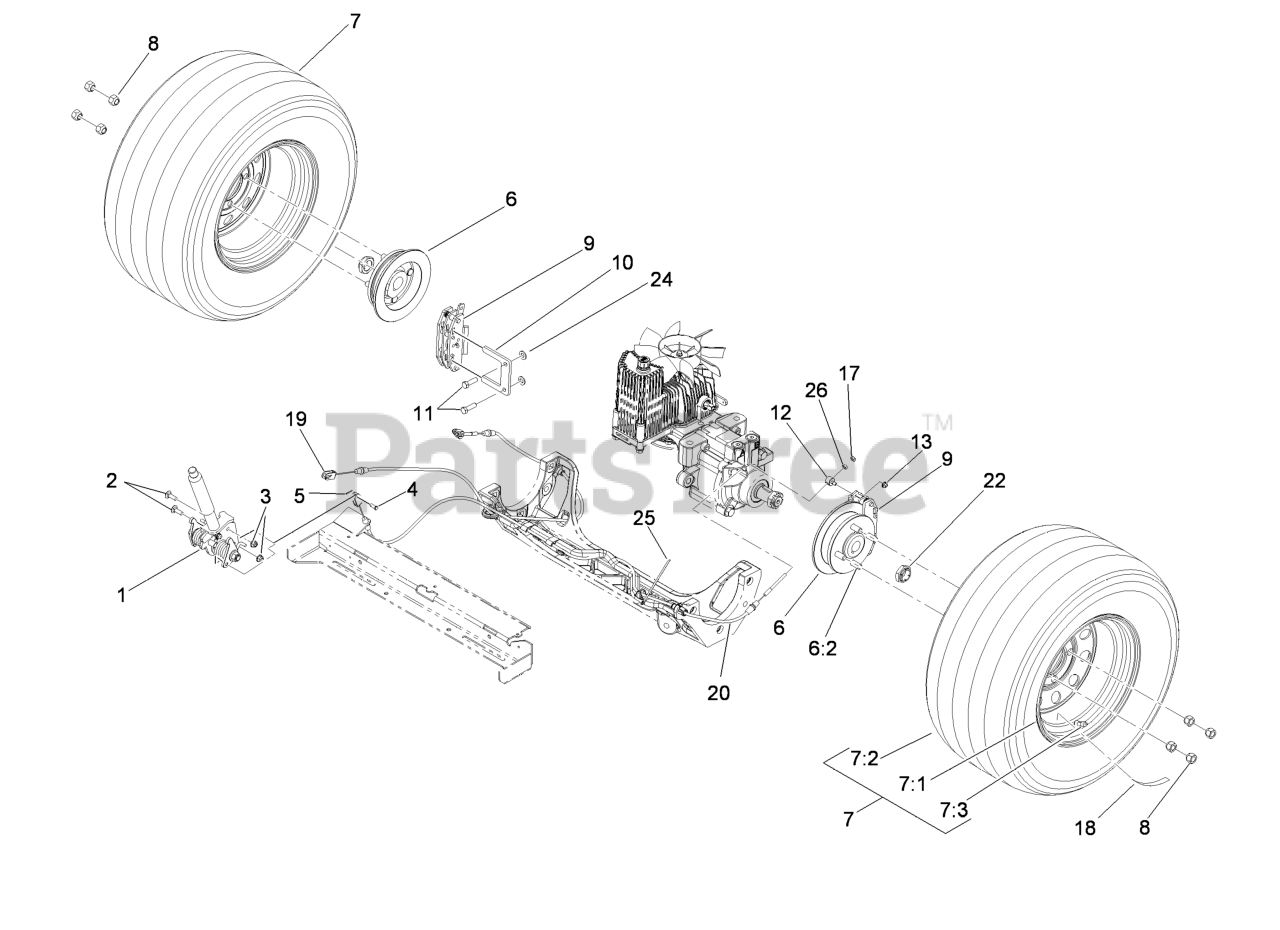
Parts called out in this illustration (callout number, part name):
1	BRAKE HANDLE ASM
2	BOLT-CARR
3	NUT-HF, NI
4	PIN-CLEVIS
5	PIN-COTTER
6	WHEEL HUB ASM
6:2	STUD-WHEEL
7	WHEEL AND TIRE ASM
7:3	Stem-Valve
8	NUT-LUG
9	CALIPER-BRAKE
10	PLATE-MOUNT, BRAKE
11	SCREW-LOCK, PATCH
17	NUT-LOCK, NI
22	LOCKNUT
24	WASHER-FLAT
25	TIE-CABLE
26	NUT-HEX
